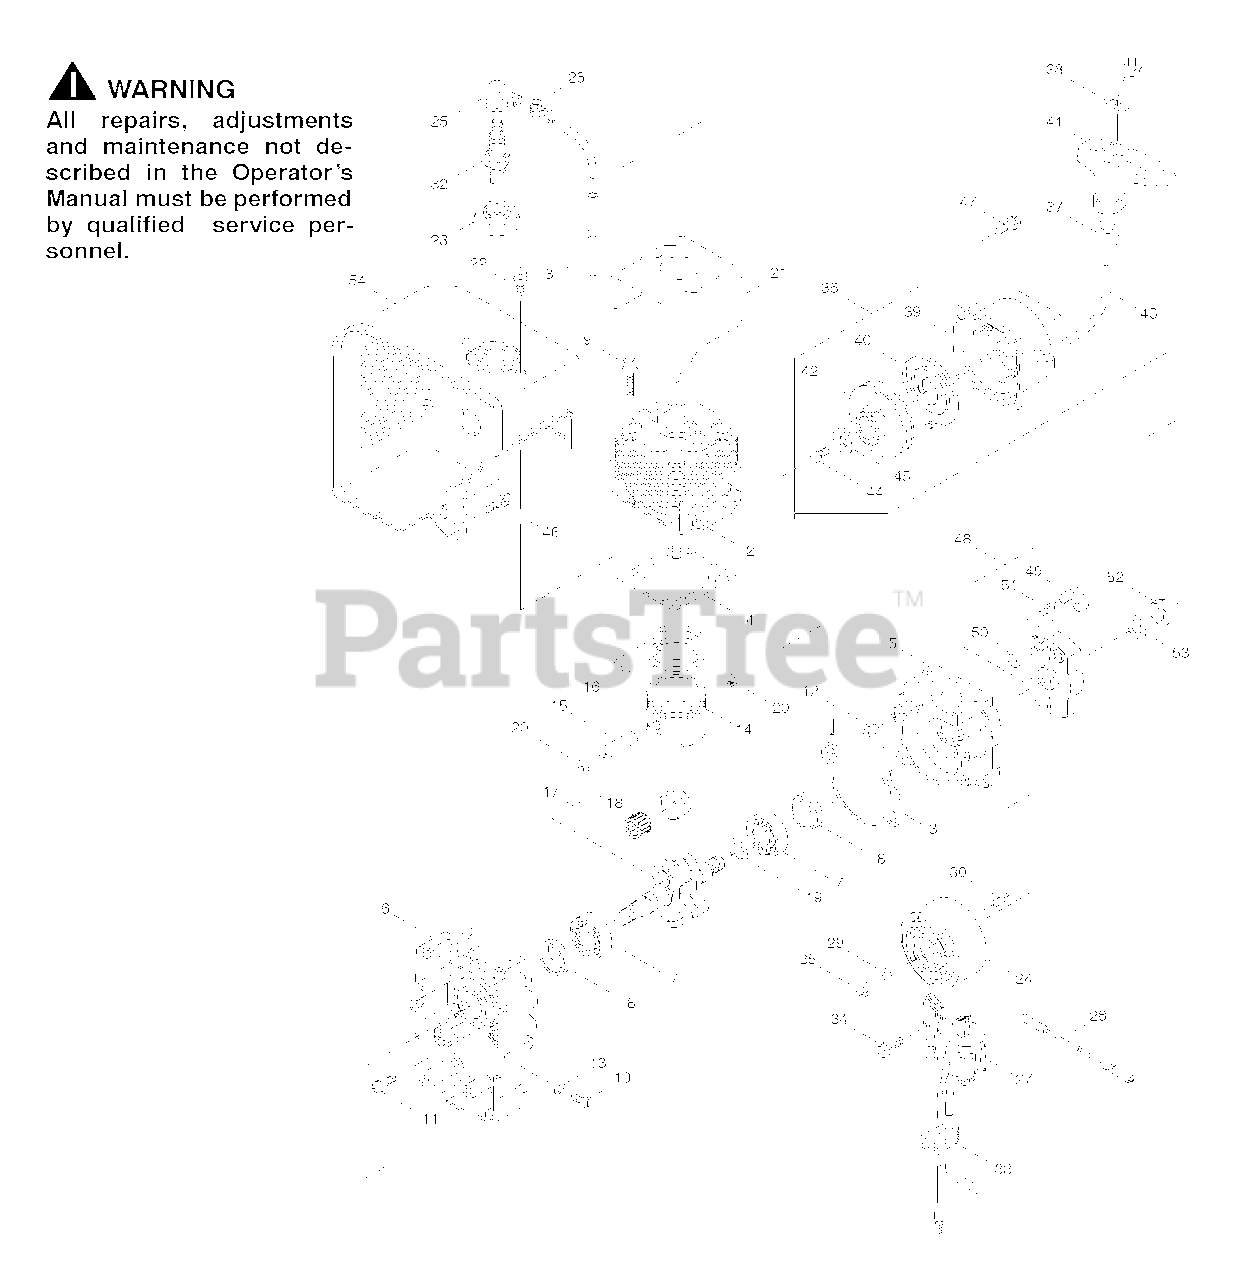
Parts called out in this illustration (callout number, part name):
2	Cylinder
5	Crankcase
6	Crankcase
8	Oil Seal
10	Screw
11	Screw
12	Dowel Pin
13	Gasket
15	Piston Pin
16	Piston Ring Set
17	Crankshaft Assy.
18	Needle Bearing
19	Shim
19	Shim 0.10mm
19	Shim 0.20mm
19	Shim 0.40mm
19	Shim 0.60mm
20	Snap Ring
21	Shroud-Heat Shield
22	Bolt
24	Flywheel
25	Spark Plug Cap
26	Terminal
27	Ignition Coil Assy.
28	Leadwire
32	Spark Plug
35	Nut
36	Assy-Recoil Starter
37	Rope Guide
39	Recoil Starter Case
40	Recoil Spring
48	Starter Pulley
50	Snap Ring
51	Return Spring
52	Nut
53	Washer
